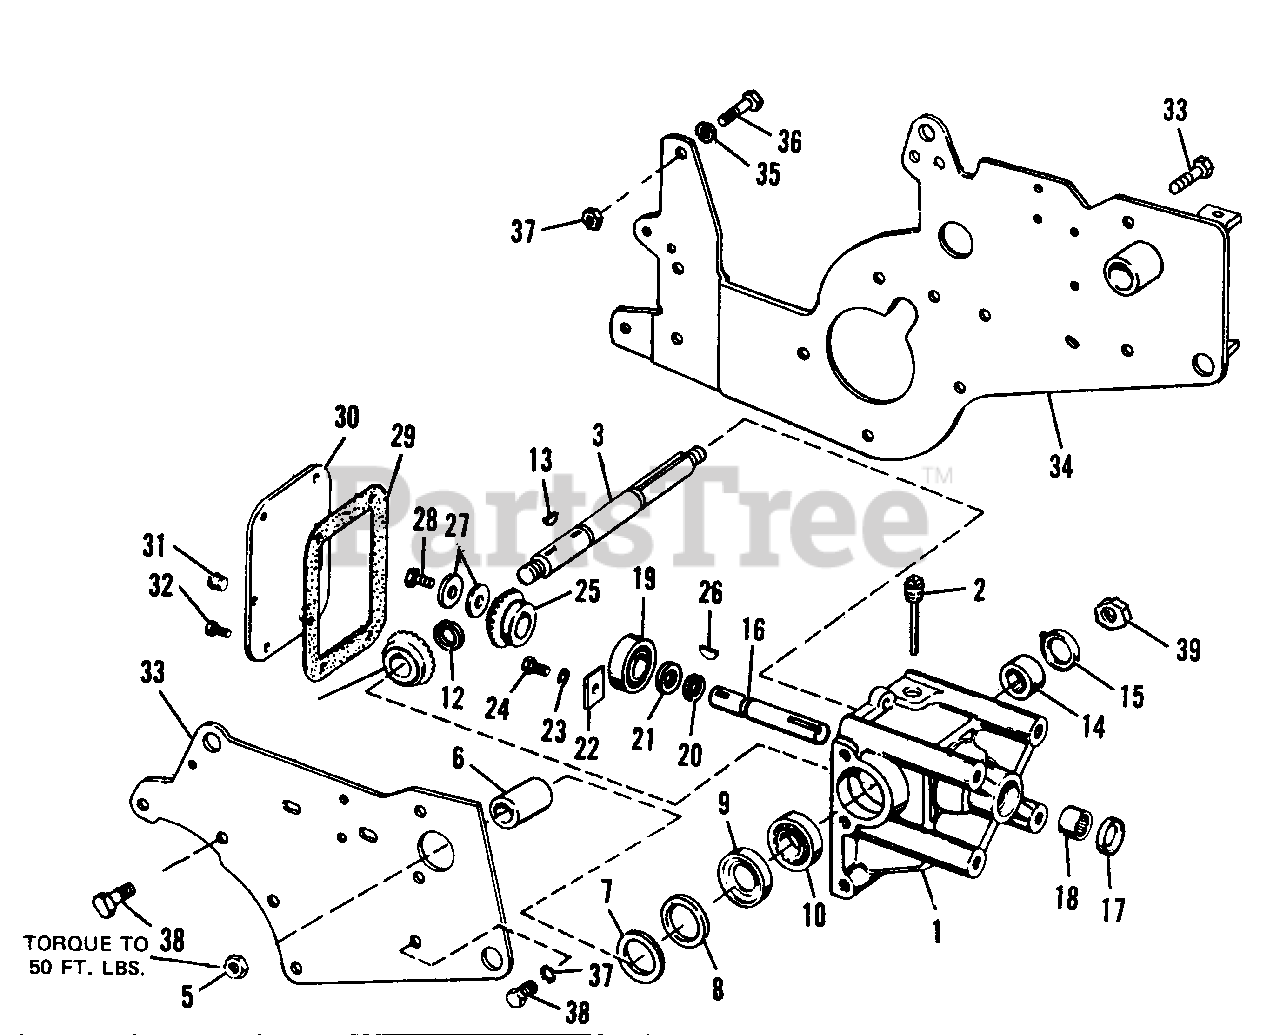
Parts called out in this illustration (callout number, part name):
1	BEVEL GEAR, Housing
2	PLUG ASSEMBLY, Filler
3	SHAFT, Driven
5	NUT, Hex, Jam, 3/4"-16
6	SPACER, Pulley
7	SHIM (As Required)
10	BEARING, Ball
11	GEAR, Bevel, Driven
12	RETAINING, Ring
13	KEY
14	BEARING, Needle
16	SHAFT, Driver
18	BEARING, Needle
19	BEARING, Ball
20	RETAINING, Ring
22	PLATE, Bearing, Clamp
23	LOCKWASHER, 5/16"
24	CAPSCREW, Hex, 5/16"-18 x 5/8" lg.
25	GEAR, Bevel, Driver
26	KEY
28	CAPSCREW, Hex, 5/16"-18 x 3/4" lg.
32	CAPSCREW, Hex, 1/4"-20 x 5/8" lg.
33	PLATE, Side, R.H.
34	PLATE ASSEMBLY, Side, L.H.
35	LOCKWASHER, 7/16"
36	CAPSCREW, Hex, 7/16"-14 x 1" lg.
37	NUT, Hex, Full, 7/16"-14
38	CAPSCREW, Hex, 7/16"-14 x 1-1/4" lg.
39	NUT, Jam, Lock
